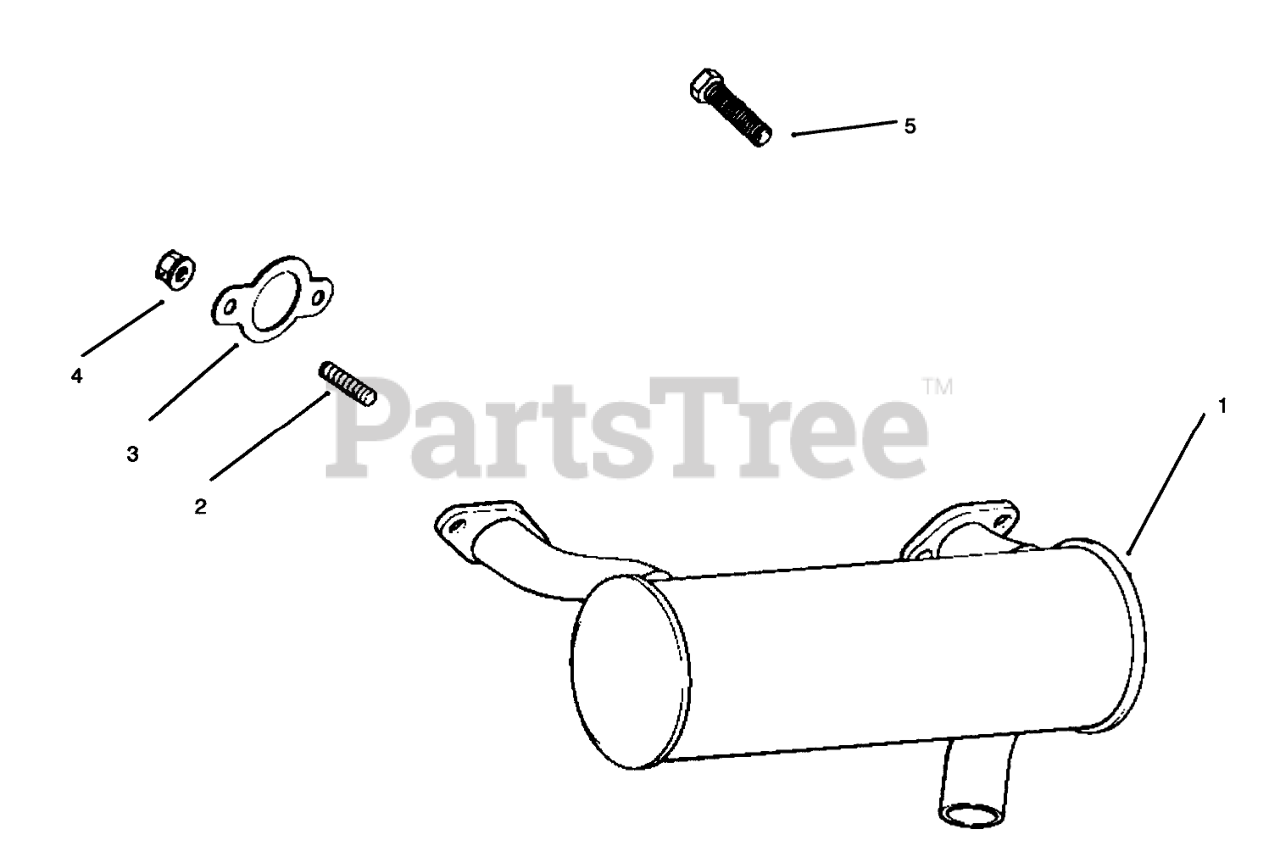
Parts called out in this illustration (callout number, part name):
1	Muffler
2	Stud
3	Gasket-Exhaust
4	Nut
5	Screw, tank bracket - starter end
